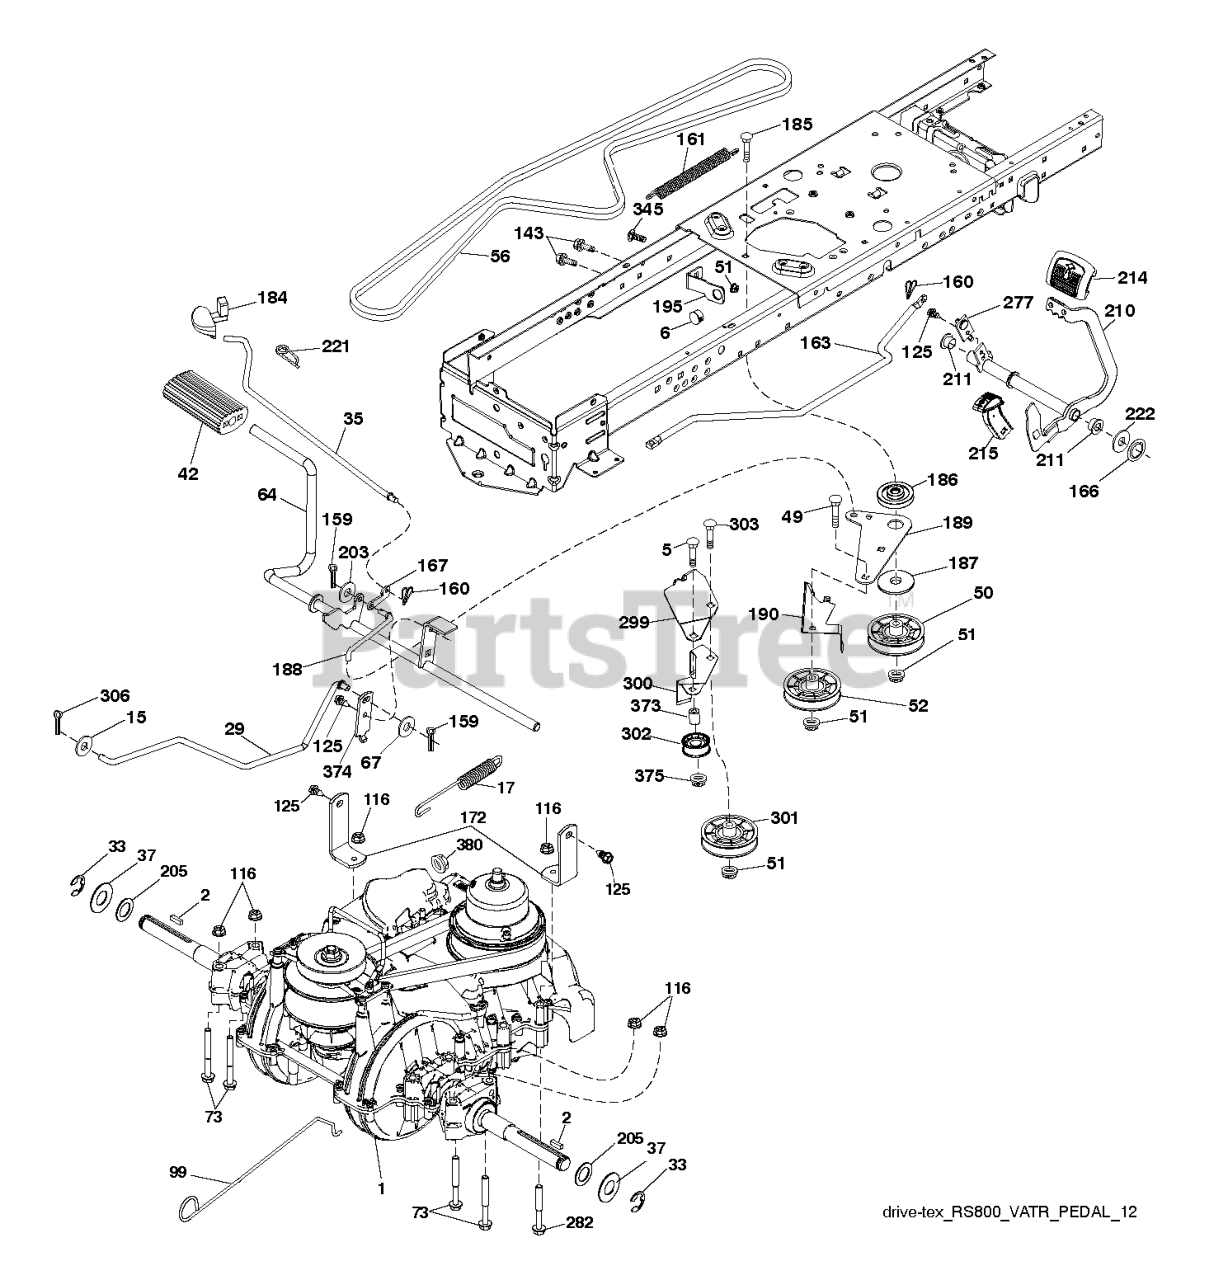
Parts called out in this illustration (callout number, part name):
2	SQUARE KEY
6	BUSHING.SNAP.NYL.BLK.
15	WASHER
17	SPRING BRAKE VARIATOR
29	BRAKE.VARIATOR.SD3
35	ROD .BRAKE. PARKING. GT. HUSQ.
37	WASHER.HARDENED
42	PEDAL COVER T
49	BOLT
50	IDLER.FLAT.910.OFFSET
51	NUT LOCK FLG 3/8-16 UNC
52	IDLER.V-GROOVE.910.OFFSET
56	BELT.DRIVE.MOWER.TEX.42"
64	SUBASM.SHAFT.PEDAL.BRAKE
67	WASHER
73	BOLT HEX 5/16-18 GR 5
99	ROD.BYPASS.VARIATOR.GEN2
116	NUT LOCK HEX FLANGE 5/16-18
125	SCREW
143	SCREW LT
159	COTTER PIN
160	RETAINER CLIP
161	SPRING, RETURN LT
163	ROD.CONTROL.PEDAL.VARIATOR
166	NUT.PUSH.625
167	LATCH.BRAKE.SPRING
172	STRAP.TORQUE.VARIATOR
184	HANDLE.PARKING.BRAKE.H (BLK)
186	SPACER.RETAINER
187	WASHER 12/32X2X10GA
188	RP.LINK.CLUTCH.GROUND.DRIVE
189	BELLCRANK.GROUND.DRIVE.TEX.
190	KEEPER.BELLCRANK.DRIVE
195	BRACKET.BRAKE.BRAKE.VAR.SD
203	WASHER
210	WELDMENT.PEDAL.VARIATOR
211	BEARING.NYLON
214	PEDAL.FORWARD.PAD.TEX
215	CAP.PEDAL.REVERSE.VARIATOR
221	RETAINER.SPRING.CLIP.H
222	WASHER 21/32 X 1-1/4 X 10 GA.
277	SUBASM.LINK.ROCKER.PEDAL
282	BOLT HEX FLGHD 5/16-18X3 GR. 5
299	BRACKET.MOUNT.IDLERS
300	KEEPER.IDLERS.REAR.VARIATOR
301	PULLEY.IDLER.V-GROOVE
302	PULLEY.IDLER.FLAT.2"
303	BOLT CARRIAGE
306	PIN COTTER
345	BOLT
373	SPACER.IDLER
374	ARM.CONTROL.BRAKE
375	LOCKNUT
378	NUT.PUSH.8MM
